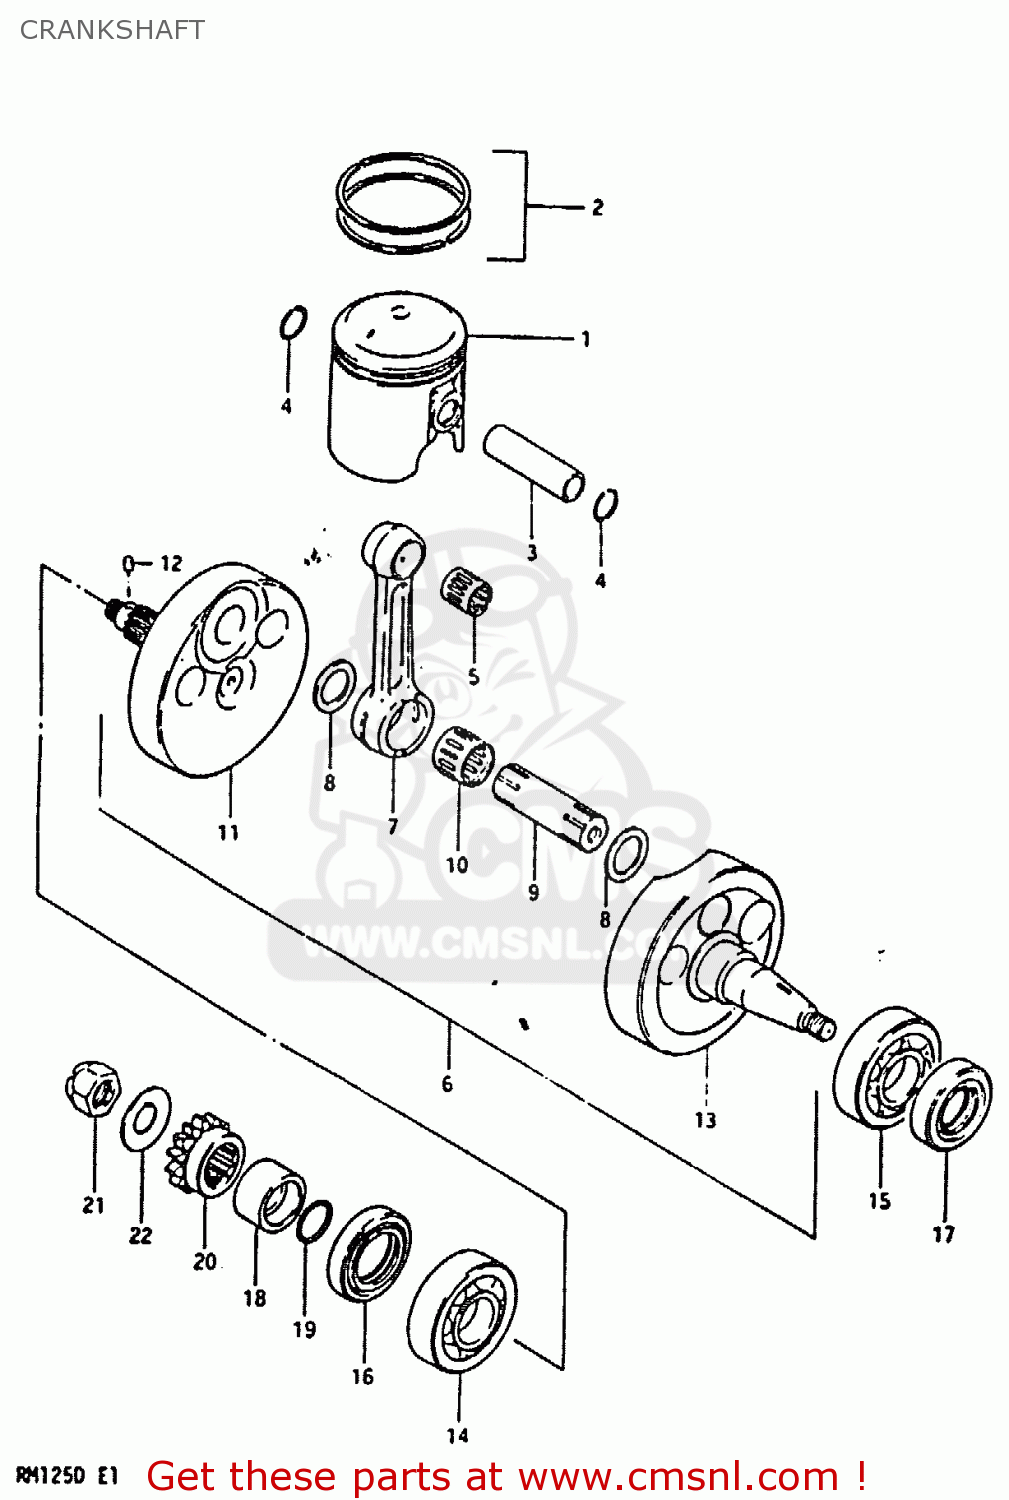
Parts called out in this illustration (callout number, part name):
1	PISTON
2	RING SET,PISTON
3	PIN,PISTON
4	RING,SNAP 14MM
5	BEARING
6	CRANKSHAFT ASSEMBLY
7	CONNECTING ROD
8	WASHER(19X34X1)
9	PIN,CRANK
10	BEARING
11	CRANKSHAFT
12	PIN 3X5
13	CRANKSHAFT,LEFT
14	BEARING
15	BEARING
16	SEAL,OIL(28X40X8)
17	SEAL,OIL(18X30X8)
18	SPACER,PRIMARY DRIVE GEAR
19	O RING(D:2.4,ID:19.8)
20	GEAR,PRIMARY DRIVE
21	NUT
22	WASHER
